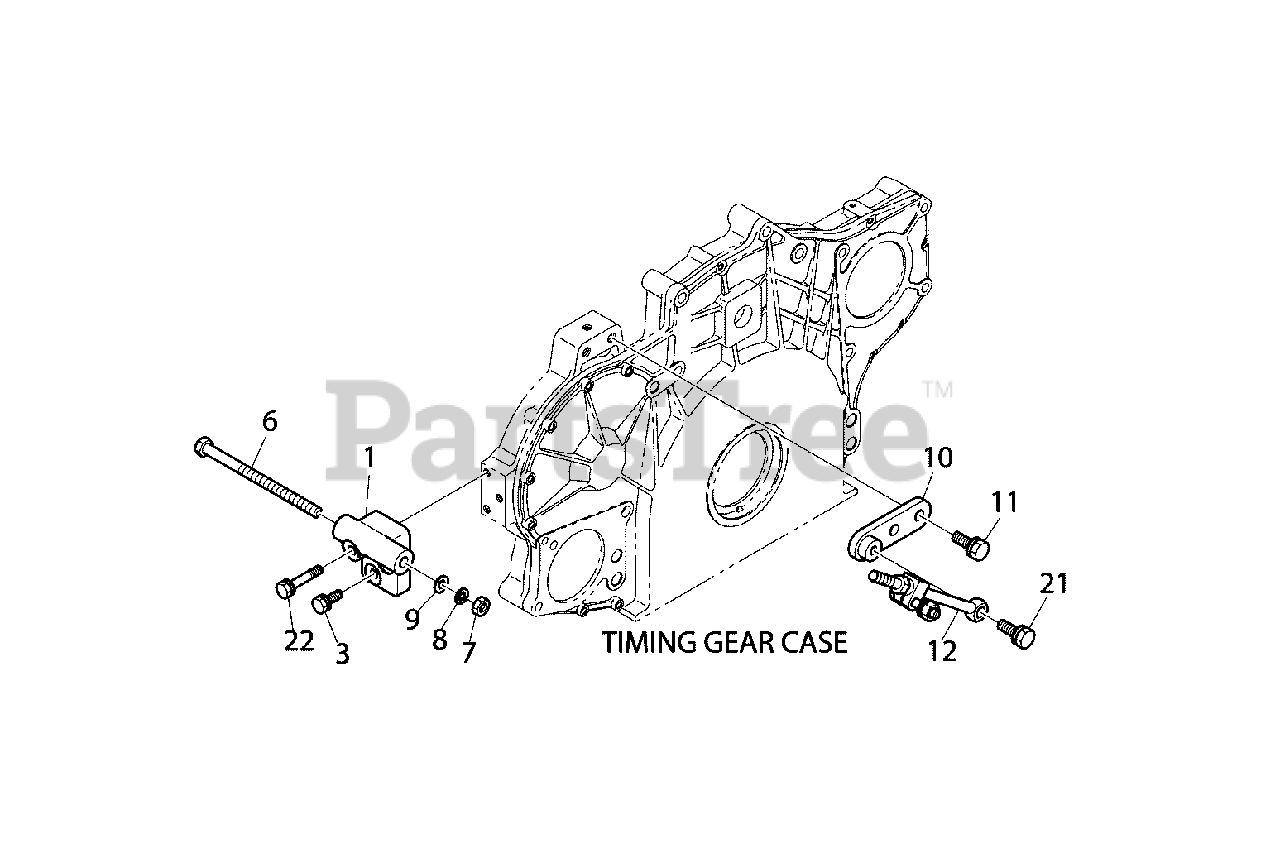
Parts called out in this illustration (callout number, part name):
1	* BRACKET, ALTERNATOR MOUNT
3	* BOLT
6	* BOLT, HEX
7	* NUT, HEX
8	* WASHER, SPRING
9	* WASHER, SPRING
10	* SUPPORT, ALTERNATOR
11	* BOLT
12	* ROD,THREAD ADJ.
21	* BOLT
22	* BOLT
